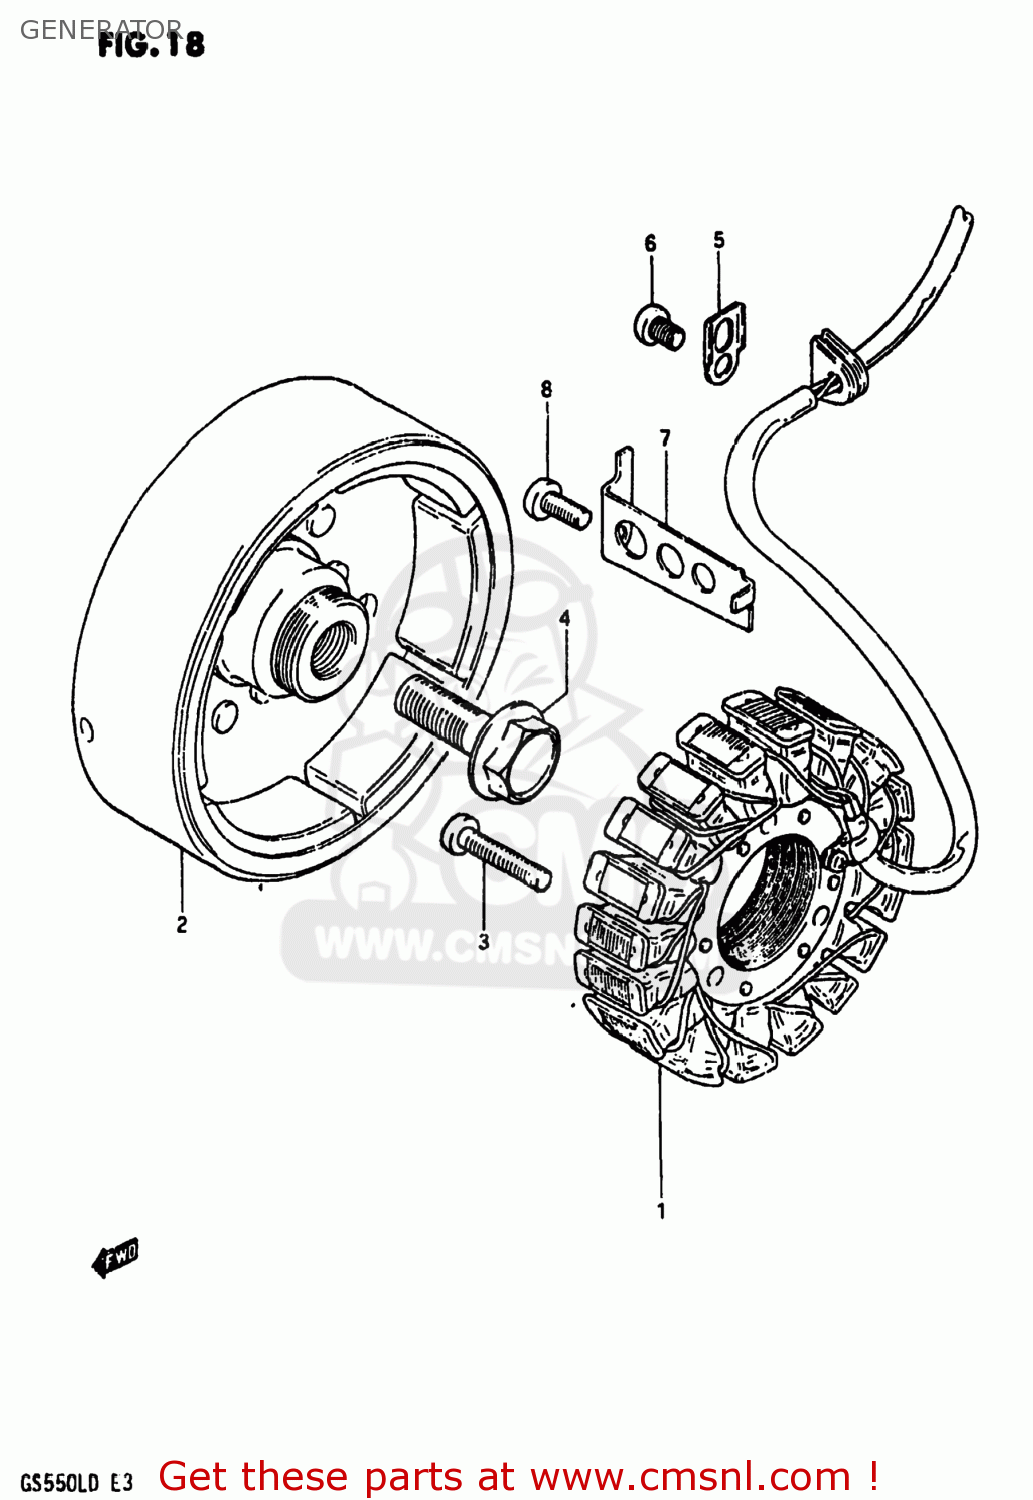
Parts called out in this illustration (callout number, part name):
1	STARTER ASSY
2	ROTOR ASSEMBLY
3	SCREW 6X30
4	BOLT(14X43)
5	CLAMP,GENERATOR LEAD WIRE
6	SCREW
7	CLAMP,GENERATOR LEAD WIRE
8	SCREW
